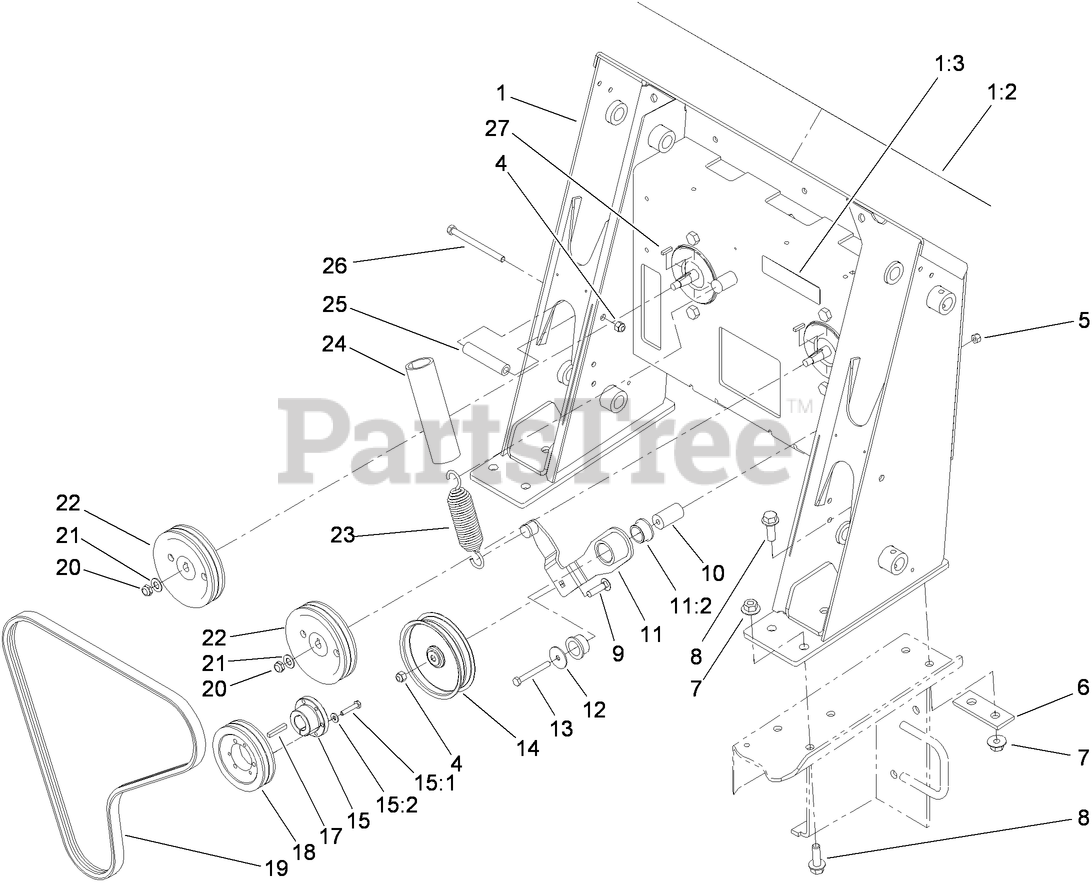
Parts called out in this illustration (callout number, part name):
1	LOADER TOWER ASM
1:2	DECAL-PANEL, CONTROL
1:3	DECAL-DANGER
4	NUT-LOCK, NI
5	NUT-LOCK, NI
6	PLATE-STIFFENER
7	NUT-LOCK, FLANGE
8	SCREW-HHF
9	SCREW-CARR
10	SPACER-MOUNTING
11	IDLER ARM ASM
11:2	BUSHING-FLANGE
12	WASHER-FLAT
13	SCREW-HH
14	PULLEY-IDLER
15	BUSHING
15:1	SCREW-HH
15:2	WASHER-LOCK
17	KEY-SQUARE
18	PULLEY
19	V-BELT
20	NUT-LOCK, NI
21	WASHER-FLAT
22	PULLEY
23	SPRING-EXTENSION
24	RETAINER-SPRING
25	TUBE-SPACER
26	SCREW-HH
